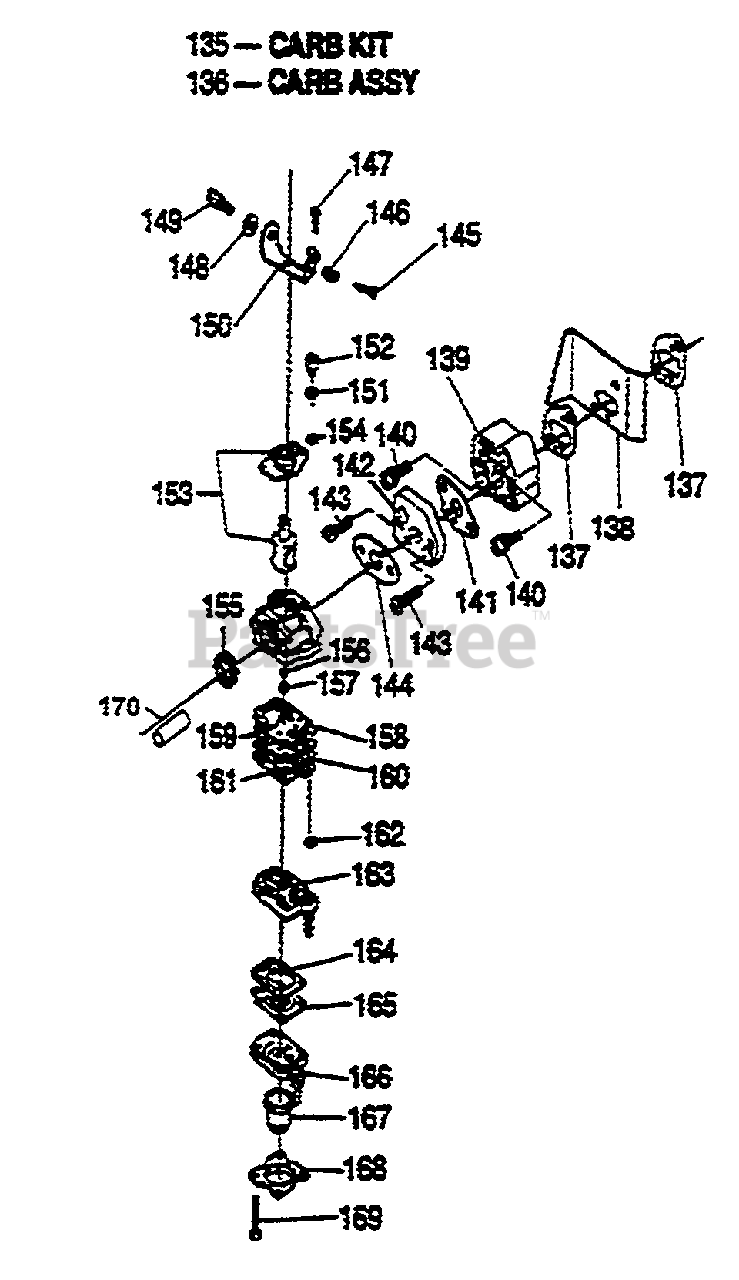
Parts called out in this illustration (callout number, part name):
136	CARB ASSY
137	GASKET, INSULATOR
139	INSULATOR
140	SCREW & WASHER
141	GASKET, CARB.
144	GASKET, CARB.
145	SCREW, IDLE
146	SPRING, IDLE
148	NUT, CABLE ADJ.
149	ADJUSTER CABLE
153	VALVE, THROTTLE
154	RING, SWIVEL
158	GASKET, PUMP
159	DIAPHRAGM
162	SCREEN, INLET
163	BODY ASSY.
164	GASKET, DIAPH.
165	DIAPHRAGM
166	BODY PRIMER PUMP
167	PRIMER PUMP
168	PRIMER PUMP COVER
169	COVER SCREW
171	HIGH ALTITUDE JET
172	HIGH ALTITUDE JET
